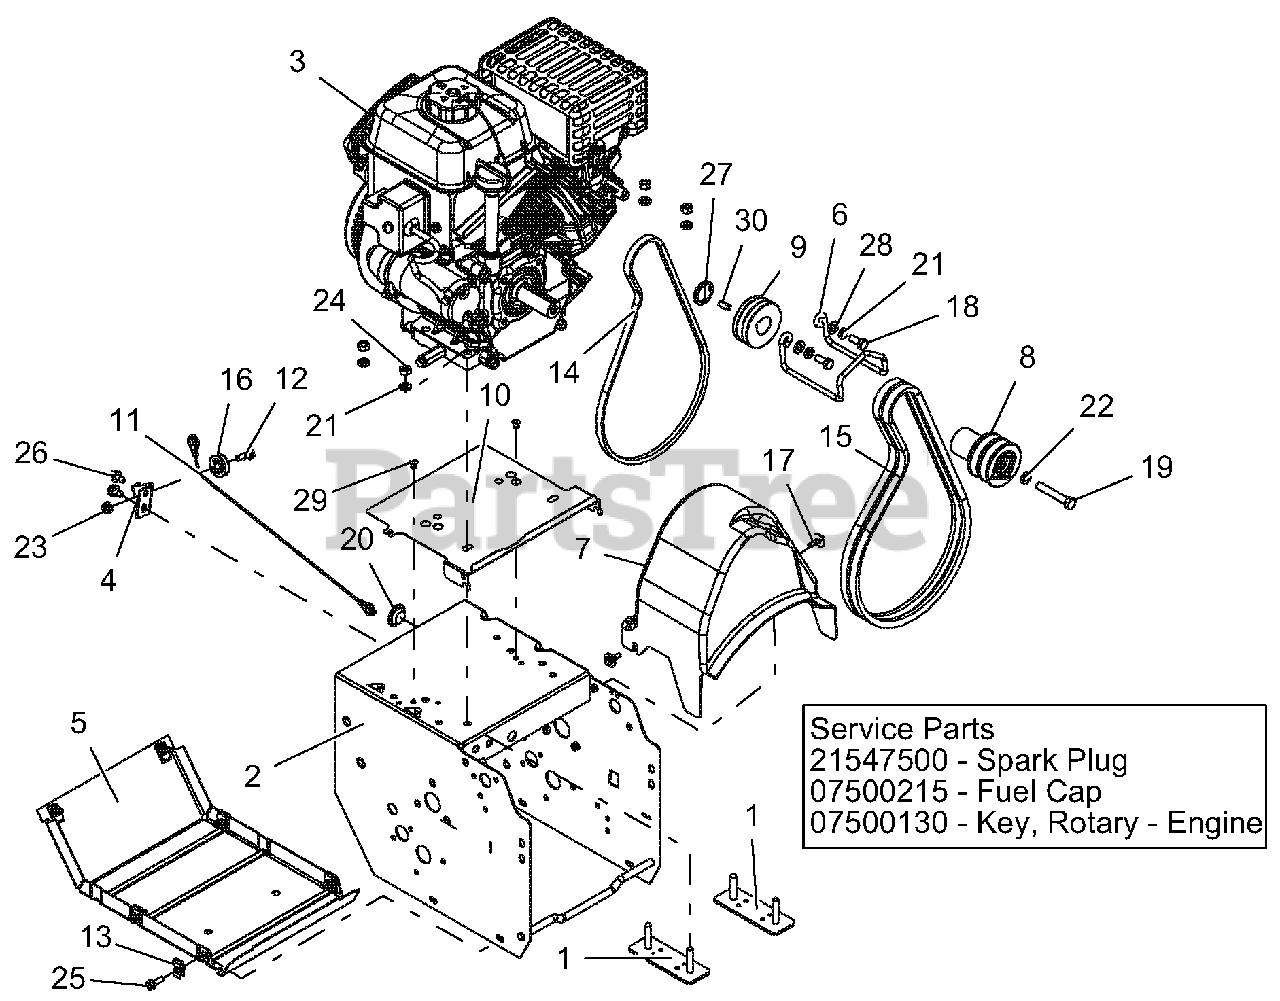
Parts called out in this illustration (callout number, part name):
1	STRAP,ENGINE BOLT,ARIENS SML
2	WELDMENT, FRAME - DLX HYBRID
3	ENGINE, ARIENS AX254 240V/60W
4	BRACKET, CABLE PULLEY
5	COVER, BOTTOM
6	FINGER, BELT
7	BELT COVER
8	SHEAVE,ATTACHMENT 2-GRV
9	SHEAVE DRIVE
10	BAFFLE,ENGINE,ARIENS SML BLOCK
11	CABLE, LOWER TRACTION (DELUXE)
12	BOLT, SHLDR-.375X.375X.25-20
13	NUT-RTNR .25-20X.56
14	V-BELT, 3L-WRAPPED
15	V-BELT, HA-RAW EDGE (SET)
16	PULLEY, CABLE
17	SCR-TAP .25-20X.5 CAPTIVE
18	BLT-HEX .31-24X.75 YWZC GR5
19	BLT-HEX .38-24X2.25 YWZC GR5
20	PLUG, HOLE - .875" NYLON
21	WSHR-LK .312X.097 HVY YWZC
22	@WSHR-LK .38X.094 REG YWZC
23	@NUT-LK-CTR-FLG .25-20 YWZC
24	@NUT-HEX .31-18 YWZC
25	BLT-HEX .25-20X.75 HWH YZ GR5
26	@SCR-TAP .31-18X.50 HWH TR YWZ
27	WSHR-FL-NYL 1.03 X 1.31 X .134
28	@WSHR-FL-STL.344X.688X.065YWZC
29	RVT-POP .187 YZ
30	KEY-SQ .25X.625X.25 SAE 8630
